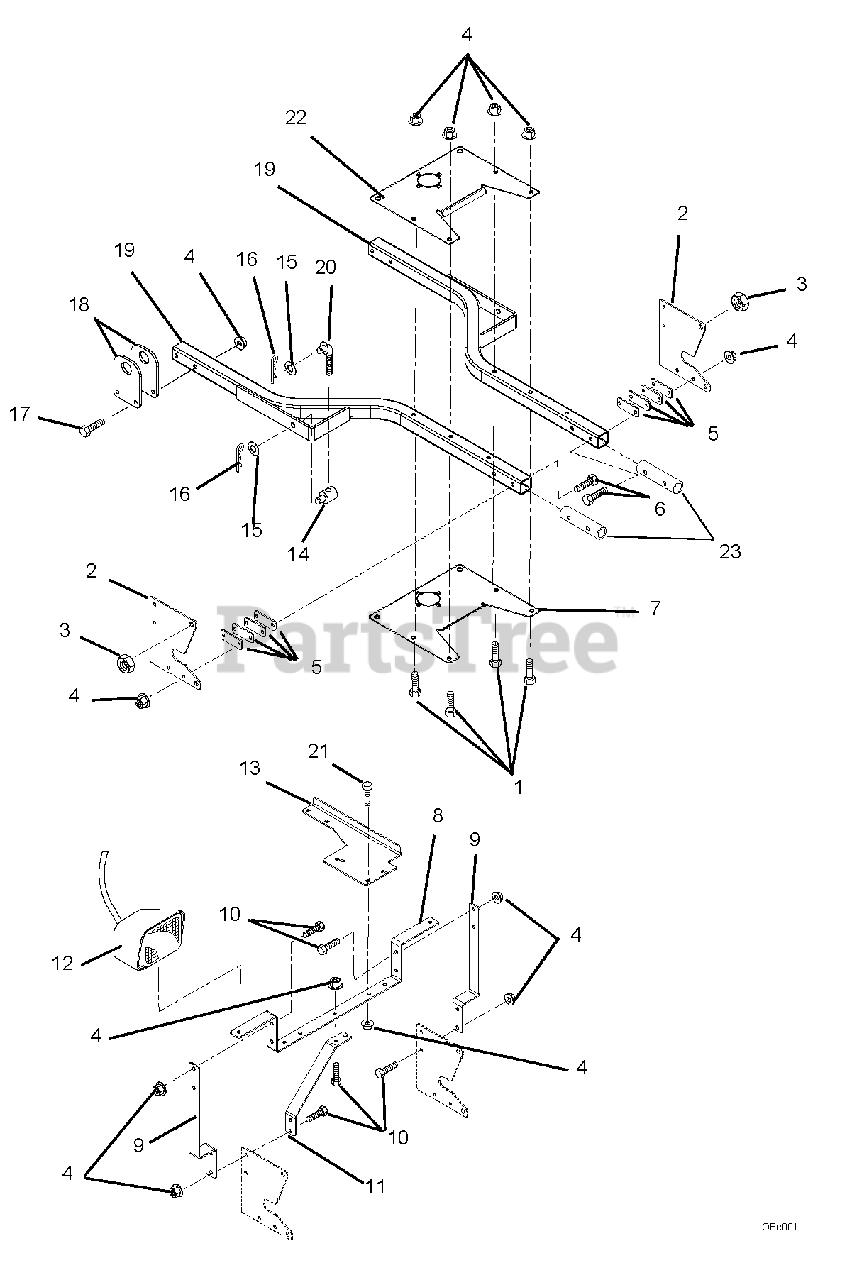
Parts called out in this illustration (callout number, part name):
1	Hex Bolt, .38-16 x 2.50 Grade 5
2	Plate, Sno-Thro Mount
3	Nut, Locking, Center .50-13
4	Nut, Locking, Top, Flange .38-16
5	Plate, Shim
6	Bolt, Hex .38-16 x 3.00 Grade 5
7	Plate, Subframe
8	Light-Bar, Snow Throw
9	Support, Light-Bar, Snow Throw
10	Bolt, Hex .38-16 x 1.00 Grade 5
11	Gusset, Light-Bar
12	Headlight
13	Bracket, Deflector Control
14	Trunnion
15	Flat Steel Washer, .531 x 1.250 x .100
16	External Hair Pin - #16 Black Zinc
17	Hex Bolt, .38-16 x 2.5 Grade 5
18	Pivot Bracket
19	Weldment, Sub-Frame Tube
20	Lift Link
21	Bolt, Round Head Square Neck .38-16 x 1.00 Grade 5
22	Plate, Subframe Top
23	Tube, Anti-Crush
